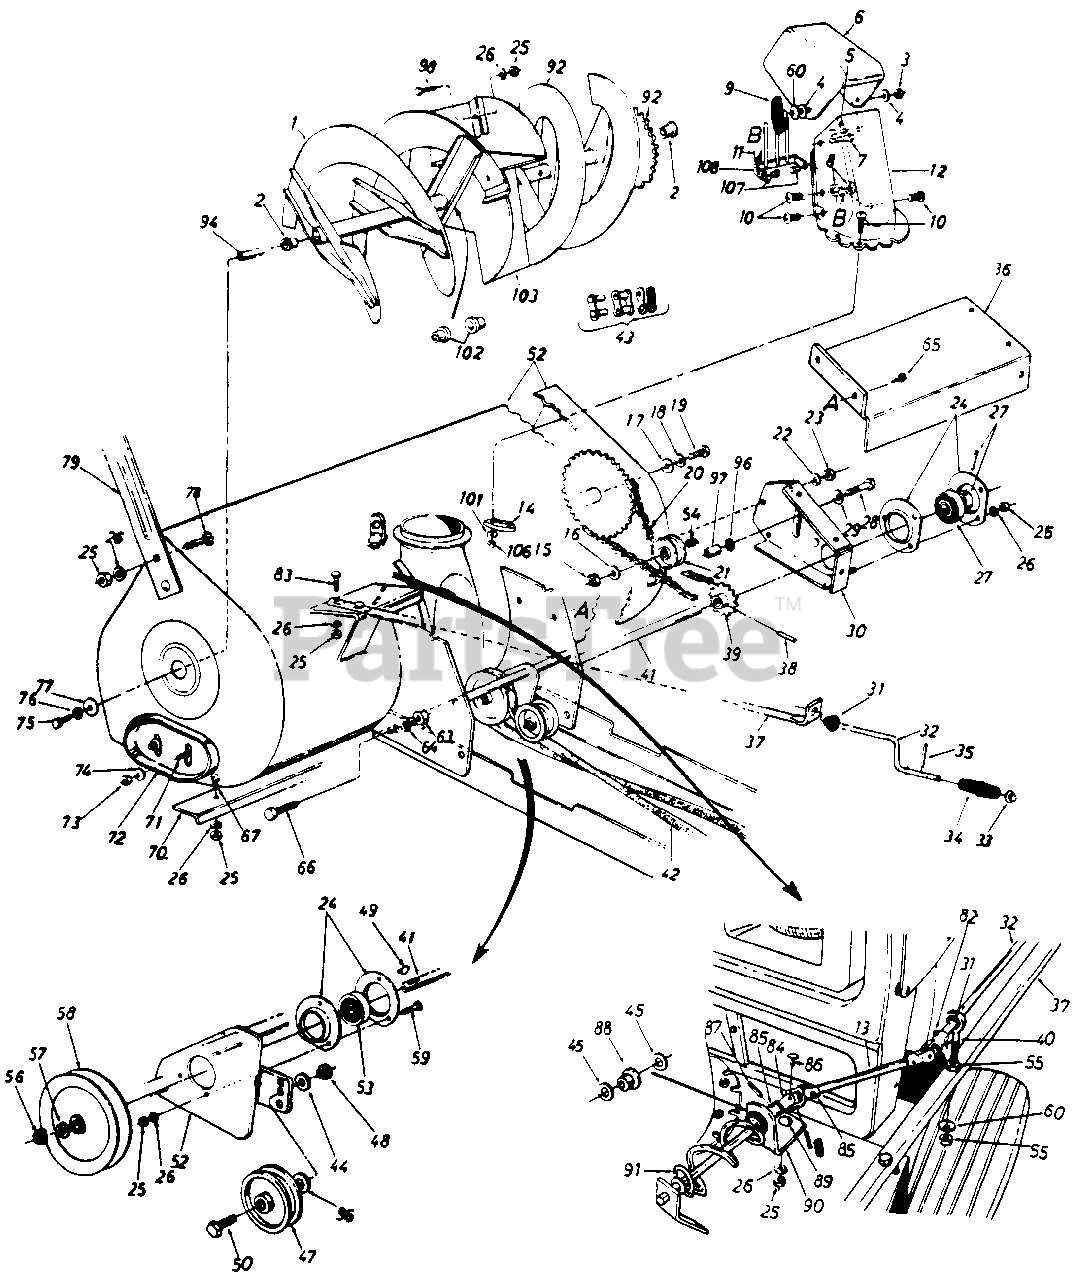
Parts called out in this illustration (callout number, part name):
3	Hex Cent. L.-Nut 5/16-18 Thd.
4	Fl.-Wash. .344" I.D.
5	Truss Mach. Scr. 5/16-18 x .75" Lg.
6	Upper Chuta
7	Carriage Bolt 5/16-18 x 1.0" Lg.
8	Hex L-Nut 1/4-20 Thd.
9	Hand Knob
10	Truss Mach. Scr. 1/4-20 x .75" Lg.
11	Ext. Spring
12	Lower Chute
13	Chute Crank Extension Rod
14	Chuta Flange Keeper
15	L.-Nut 3/8-16 Thd.
18	Bellevilla Wash.
19	Hex Bolt 1/2-13 x 1.00" Lg.
20	#420 Chain 1/2" Pitch x 77 0 Links
21	Plastic Idler 2.00" O.D.
22	L.-Wash. 1/4" I.D.
23	Hex Nut 1/4-20 Thd.
24	Bearing Housing
25	Hex Nut 5/16-18 Thd.
26	L.-Wash. 5/16" I.D.
27	Selt-Aligning Bearing
28	Hex Bolt 3/8-16 x 1.75" Lg.
29	Belleville Wash. 3/8" I.D.
32	Chute Crank .375 Dia. x 34.5" Lg.
33	Push Nut 3/8" Rod
35	Roll Pin
39	14 Teeth Sprockct As'y.
40	Eyebolt 5/11-18 x 3.0" Lg.
42	"V"-Belt
43	Master Link for #420 Chain
44	L.-Wash. 3/8" I.D.
45	Fl.-Wash. .385 I.D. x .62" O.D.
47	Fl.-ldlor with Flan5os
48	Hcx Jam L-Nut 3/8-13 Thd.
49	#61 Hi-Pro Key 3/16 x 5/8 0 Dia.
50	Hex Bolt 3/8-16 x 1.75" Lg.
52	Spiral Housing Ass'y.
53	Self-Aligning Bearing
54	Sleeve Bearing .50" I.D.
55	Hex Nut 5/16-18 Thd.
56	Hex Nut 3/4-10 Thd.
57	L.-Wash. 3/4" I.D.
58	"V"-Pulley .750" I.D. x 6.00" O.D.
59	Hex Sems Bolt 5/16-18 x .75" 4.
60	Bell.-Wash. .345" I.D. x .88" O.D.
63	Hex Nut 1/2-13 Thd.
64	L.Wash. 1/2" I.D.
65	Hex Wash. Hd. Tap Scr. 1/4-20 x .50" Lg.
66	Hex Bolt 1/2-13 x 2.75" Lg.*
67	Carriage Bolt 5/16-18 x .75"
72	Skid Shoe
73	Hex Jam Nut 3/8-16 Thd.
74	Belleville Wash. 3/8" I.D.
75	Hex Bolt 1/2-13 x 1.00" Lg.
76	Belleville Wash. 112" I.D.
78	Carriage Bolt 5/16-19 x .62" Lg.*
83	Hex Bolt 5/16-18 x 1,50" Lg.
85	Joint Bracket Ass'y.
86	Oval Head Rivet
87	Spring Pin Roll 1/8" Dia. x .75" Lg.
88	Nylon Bushing
89	Carriage Bolt 5/16-18 x .75" Lg.
90	Chuta Crank 8racket
91	Chuta Crank Ass'y.
97	Idler Spacer
98	Carrlagc Bolt 5/16-18 x .75" Lg.
101	Fl.-Wash. 1/4" I.Q
102	Plastic Bushing
107	Shld. Nut 1/4-20 Thd.
